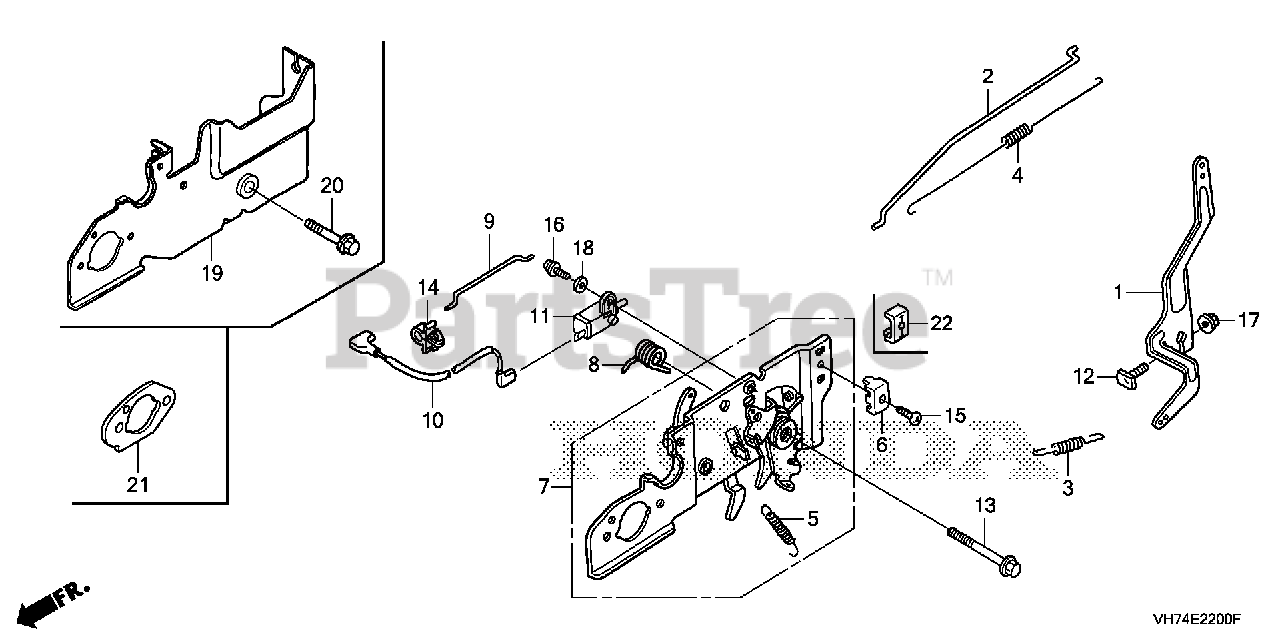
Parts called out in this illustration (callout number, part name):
1	ARM, GOVERNOR
2	ROD, GOVERNOR
3	SPRING, GOVERNOR
4	SPRING, THROTTLE RETURN
5	SPRING, LEVER
6	HOLDER, CABLE
7	BASE, CONTROL
8	SPRING, CONTROL LEVER RETURN
9	ROD, CHOKE
12	BOLT, GOVERNOR ARM
13	BOLT, FLANGE (6X45) (CT200)
15	SCREW, PAN (5X16)
17	NUT, FLANGE (6MM)
